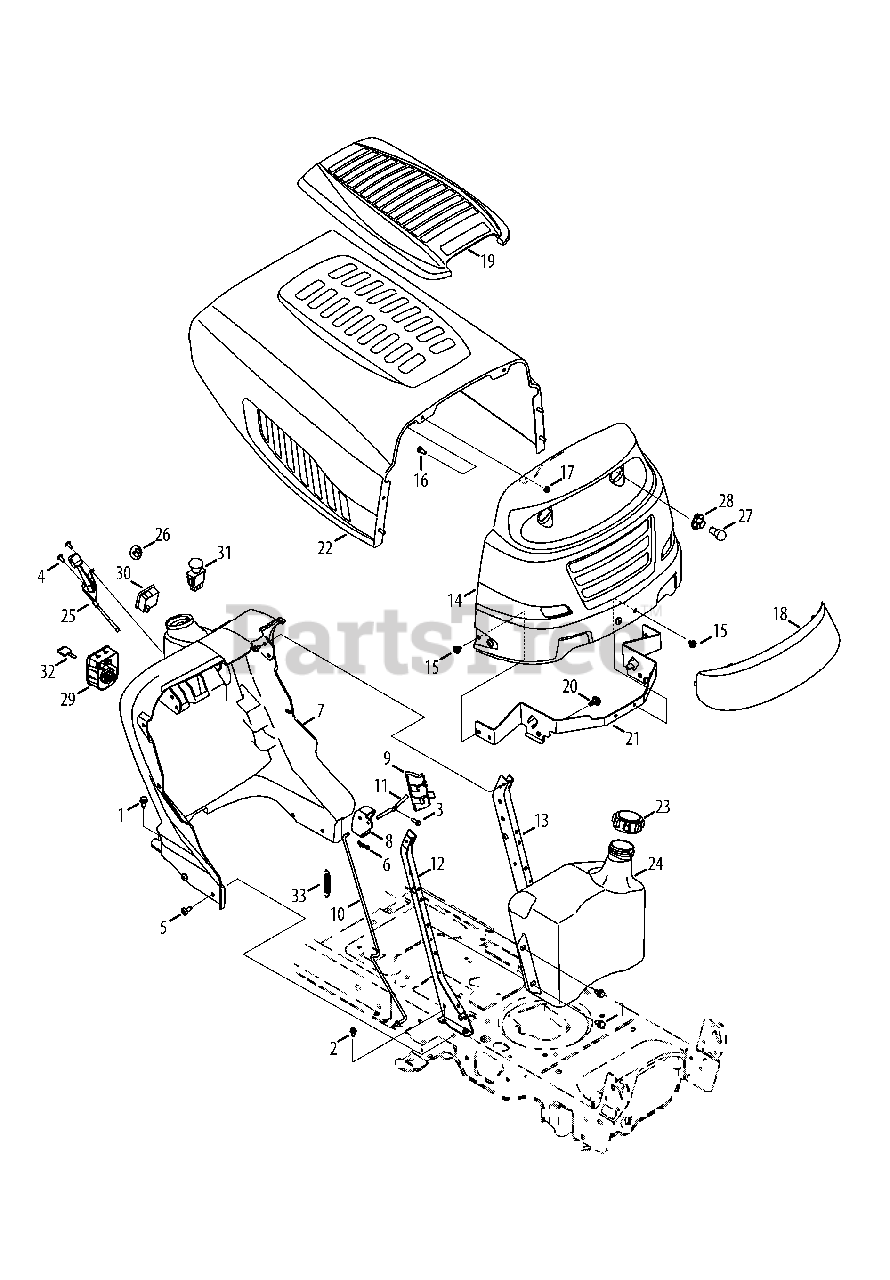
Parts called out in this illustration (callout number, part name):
1	Taptite Screw ,5/16-18:.750
2	Taptite Screw ,1/4-20:0.500
3	Hi-Lo Screw, 1/4-15:0.750
4	Screw, 1/4-14:0.625
5	Taptite Screw ,5/16-18:0.750
6	Bow Tie Cotter Pin
7	Dash Panel
8	Dash Lever
9	Cruise Cover
10	Control Rod
11	Lever
12	RH Support Plate
13	LH Support Plate
14	Grill
15	Taptite Screw ,5/16-18:0.375
16	Hex Screw, 1/4-20:.620
17	Flangelock Nut, 1/4-20
18	Grill Lens
19	Hood Scoop
20	Shoulder Screw, .43X.29:5/16-18
21	Hood Pivot Bracket
23	Fuel Cap
24	Fuel Tank
25	Throttle/Choke Control
26	Choke Plug
28	Lamp Socket
29	Key Switch
30	Hour Meter
31	Electric PTO Switch
32	Key, Assembly
33	Extension Spring, .500 DIA x 2.733 LG
